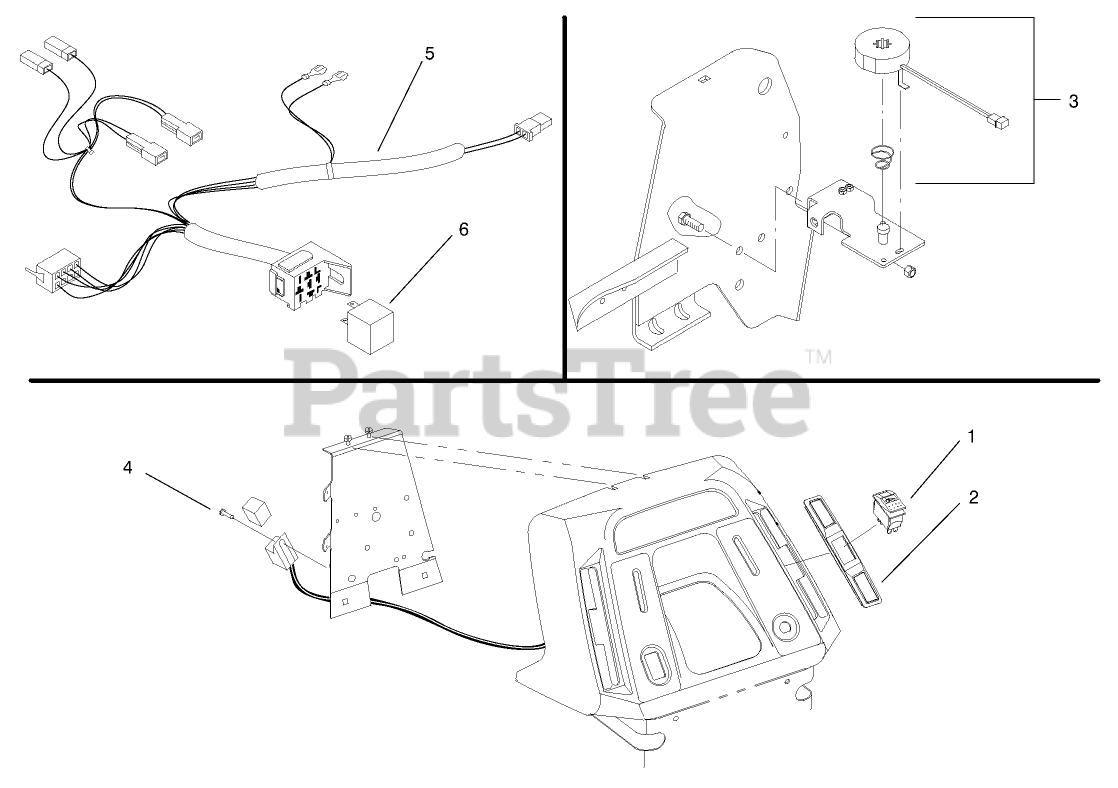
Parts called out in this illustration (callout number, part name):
1	SWITCH-CRUISE
2	COVER-SLOT, RH
3	MAGNET ASM
4	SCREW-PPHTF
5	HARNESS - WIRE
6	RELAY
